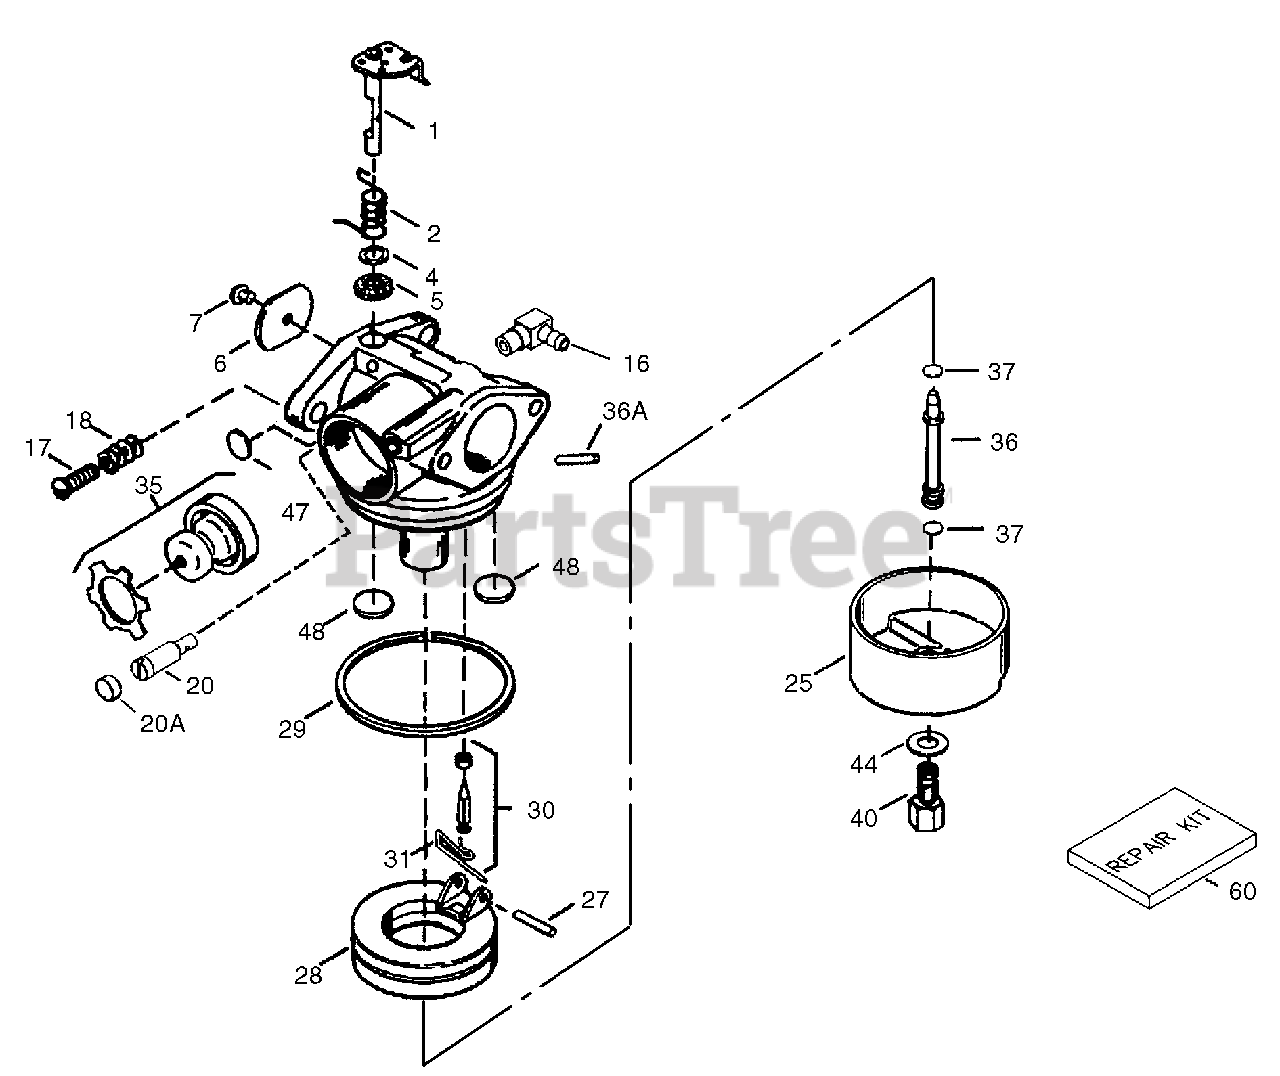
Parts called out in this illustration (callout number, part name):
1	Throttle Shaft & Lever Assembly
2	Throttle Return Spring
4	Dust Seal Washer
5	Dust Seal
6	Throttle Shutter
7	Shutter Screw
16	Fuel Fitting
17	Throttle Crack Screw/Idle Speed Screw
18	Tension Spring
20	Idle Restrictor Screw
20A	Idle Restrictor Screw Cap
25	Float Bowl
27	Float Shaft
28	Float (Plastic)
29	Float Bowl O-Ring
30	Inlet Needle, Seat, & Clip (Incl. 31)
31	Spring Clip
35	Primer Bulb (Red) /Retainer Ring
36	Main Nozzle Tube
36A	Bowl Vent Tube Extension
37	O-Ring, Main Nozzle Tube
40	High Speed Bowl Nut
44	Bowl Nut Washer
47	Welch Plug, Idle Mixture Well
48	Welch Plug, Atmospheric Vent
60	Repair kit
